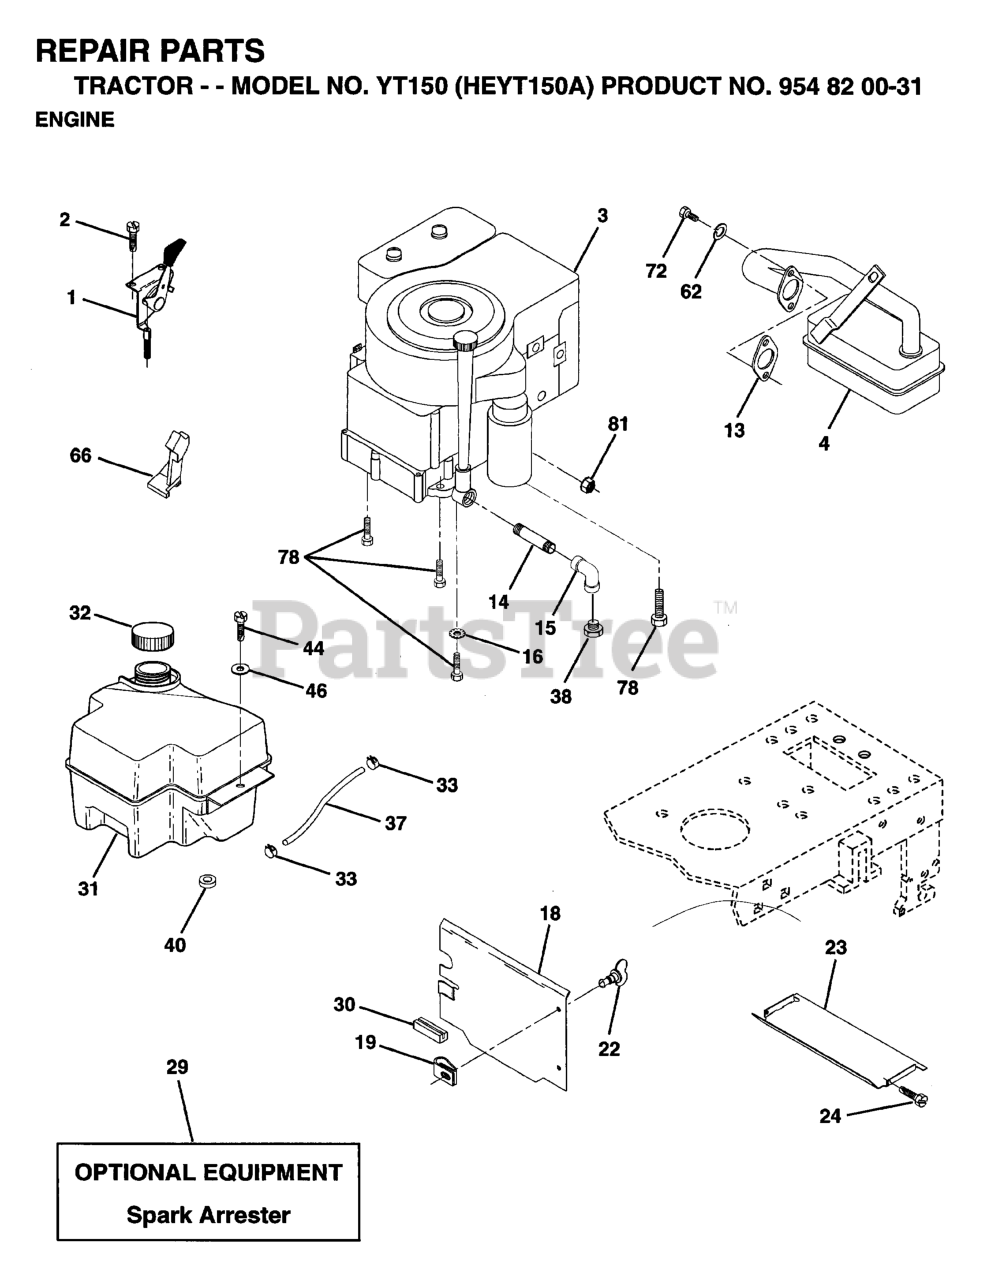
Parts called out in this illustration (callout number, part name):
1	CONTROL
2	SCREW LT
4	MUFFLER.LT.BRIGGS.14HP.IC/OHV
13	GASKET.ENG.1.313 ID.TIN PLATED
14	Nipple Pipe 3/8 Npt X 3-1/2
15	ELBOW
16	LOCKWASHER
18	HEAT SHIELD
19	RECEPTACLE LT
22	STUD 1/4 TURN
23	HEAT SHIELD
29	KIT.SPARK ARRESTOR 794945 B&S
31	FUEL TANK
32	FUEL CAP
33	HOSE CLAMP
37	LINE.FUEL.20
40	BUSHING.SNAP.NYL.BLK.
44	SCREW HEX CRT
62	WASHER.LOCK.HVY.HLCL.SPR.5/16
66	STOP THROTTLE
72	SCREW
78	SCREW
81	NUT FLANGE 1/4-20 STARTER NUT
